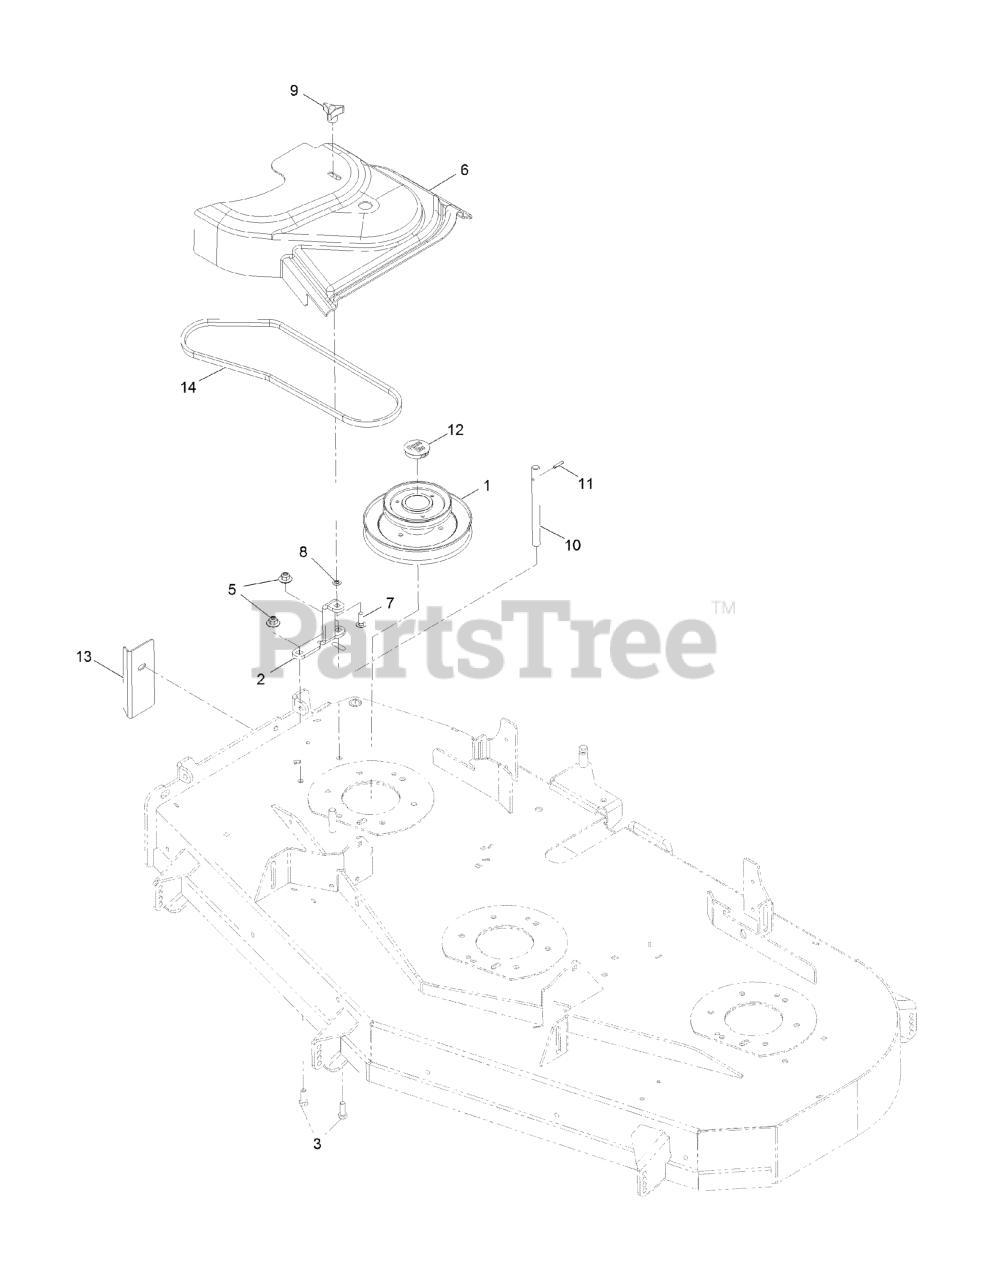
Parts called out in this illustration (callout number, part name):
1	JACKSHFT- UV DRIVE 603
2	BRACKET-BELT COVER
3	SCREW-HH
5	Nut-Nyloc 3/8-16 Flg
6	COVER-BELT UVE 60
7	BOLT-CARR
8	RING-RETAINING, BOLT
9	KNOB-3 PRONG
10	SHAFT-CATCHER, GRASS
11	PIN-ROLL
12	PLUG, BLACK NYLON 1.75
13	PLATE-BLOCKER
14	BELT- 4L SECTION
